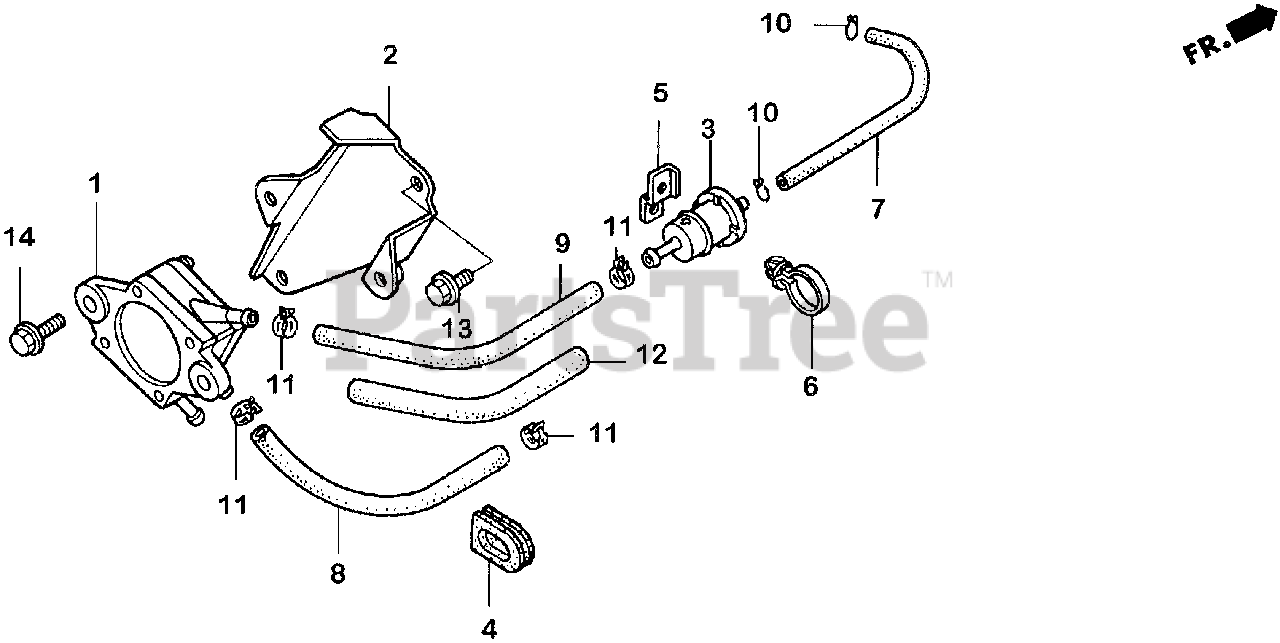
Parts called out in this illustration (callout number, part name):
1	PUMP ASSY., FUEL (MSDS)
2	STAY, FUEL PUMP (NOT AVAILABLE)
3	FILTER, FUEL
4	GROMMET, CORD
5	BASE, CLIP
6	CLIP, WIRE HARNESS
7	BULK HOSE, FUEL (4.5X3000) (Honda Code 5137104). (4.5X140)
8	BULK HOSE, FUEL (5.5X3000) (Honda Code 5338587). (5.5X150)
9	BULK HOSE, FUEL (5.5X3000) (Honda Code 5338587). (5.5X150)
10	CLIP, TUBE (B8)
11	CLIP, TUBE (10.5MM)
12	BULK HOSE, VINYL (11X13X3000) (11X13X210)
13	BOLT, FLANGE (6X8)
14	BOLT, FLANGE (6X14)
